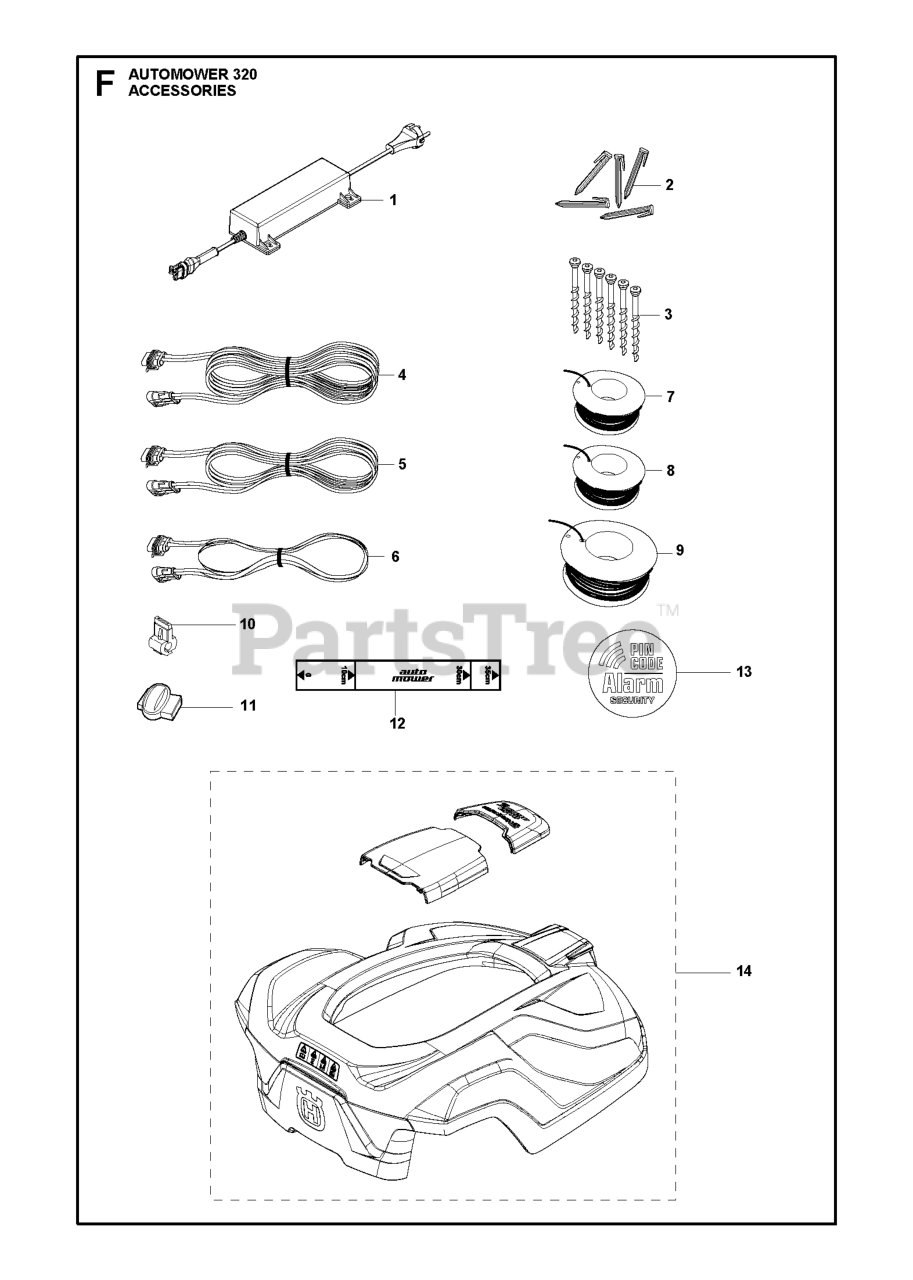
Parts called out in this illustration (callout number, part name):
2	STAPLES (100 CT BAG)
2	STAPLE 100 PCS, BLISTER
3	SCREW KIT CS
3	SCREW 3 PCS, BLISTER PACK
4	CABLE ASSY LOW VOLTAGE CABLE
5	CABLE ASSY LOW VOLTAGE CABLE
6	CABLE ASSY LOW VOLTAGE CABLE
7	WIRE 150M, BLISTER
7	LOOP WIRE 150M
8	LOOP WIRE 250M
9	WIRE 500M
10	CONNECTOR 5 PCS, BLISTER
10	BRAKER
11	COUPLER SPLICER, 5 PCS,
11	SPLICE CONNECTOR 50 PCS/PK
11	SPLICE KIT
12	RULER / CENTIMETERS
13	LABEL SECURITY
